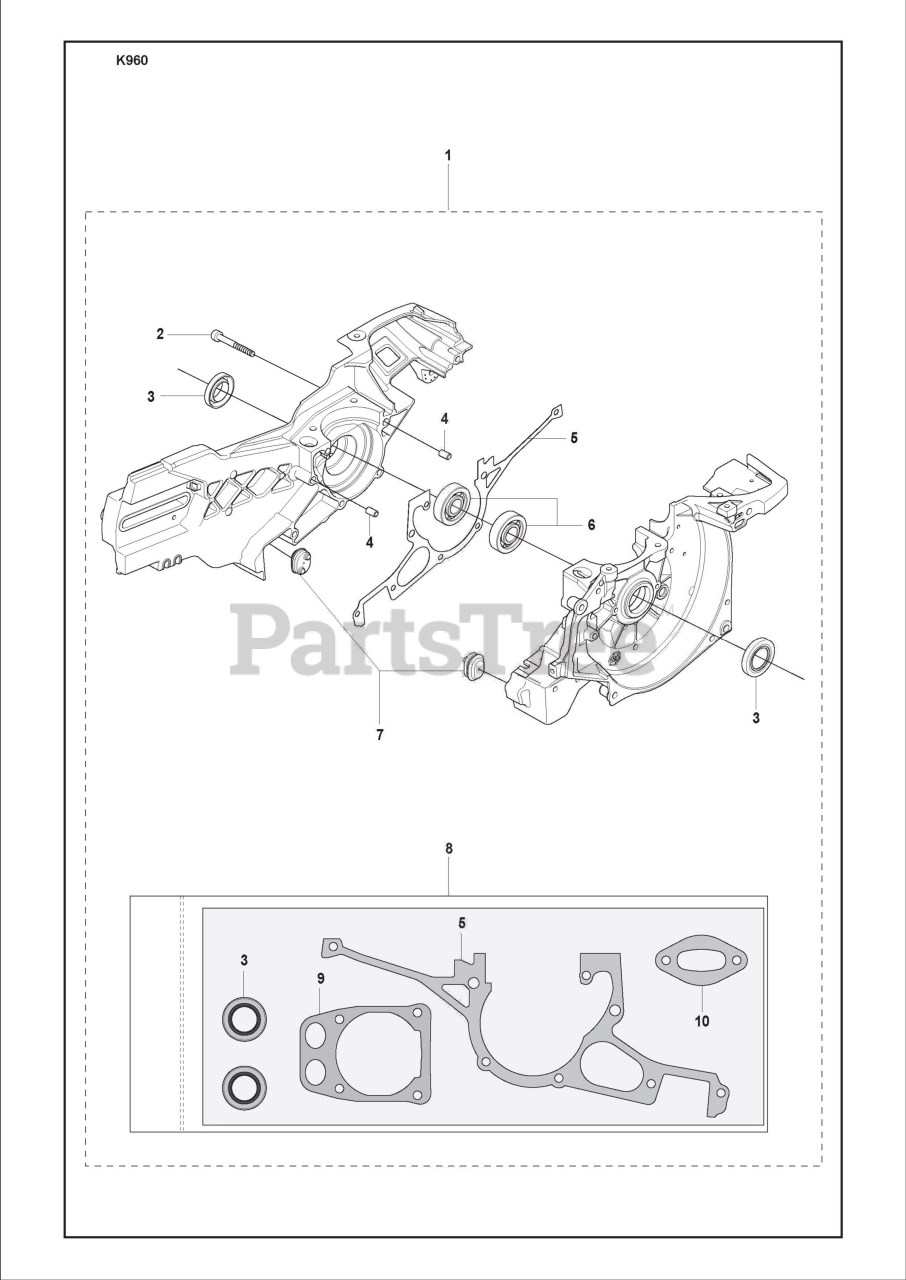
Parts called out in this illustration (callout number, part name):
1	Crankcase Assy
3	Sealing Ring
4	Guide Bushing
5	Gasket
6	Ball Bearing
7	Rubber Bushing
8	Gasket Kit
9	Gasket
10	Gasket Muffler
